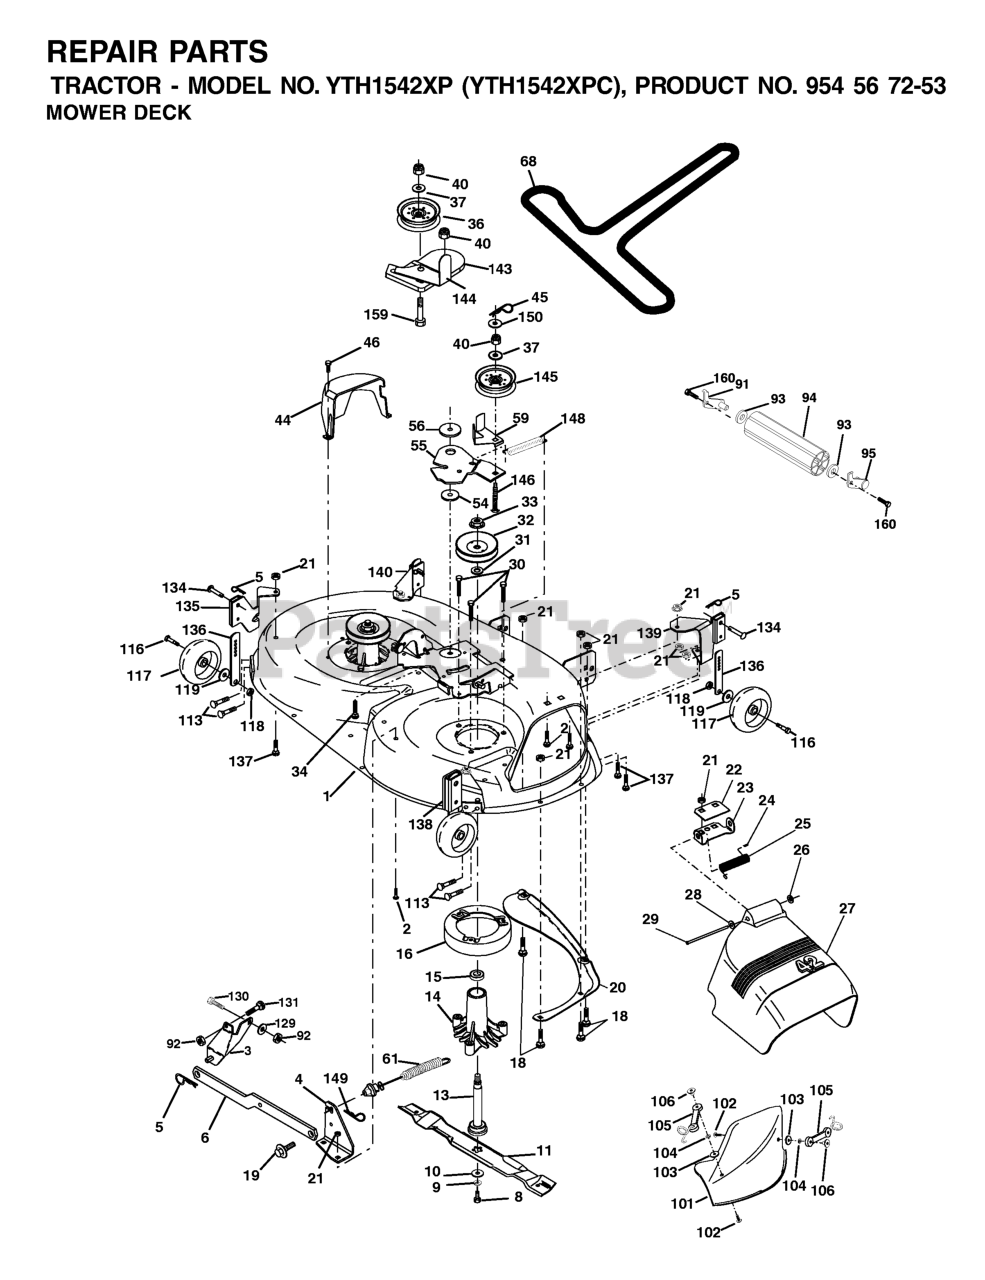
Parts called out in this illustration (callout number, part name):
1	DECK, 42"
2	RP BOLT 5/16-18 X3/4 ZN/YEL GR
3	BRKT ASM SWAY BAR
4	BRACKET SWAY BAR 42" DECK
5	RETAINER-SPRNG RB
6	BAR SWAY DECK
8	BLADE BOLT
9	LOCKWASHER
10	WASHER.BLADE
11	Blade Mower 42" High Perf.
13	SHAFT ASM VENT
14	HOUSING.MANDREL.VENTED (MACHD)
16	STRIPPER.MANDREL.ROUND.BLACK
18	BOLT
19	BOLT SHD 5/16-18
20	BAFFLE.VORTEX
21	LOCKNUT
22	STIFFENER BRACKET
23	DEFLECTOR BRACKET
24	CAP-SLEEVE LT
25	SPRING TORSION
26	NUT PUSH M
27	SHIELD DEFLECTOR
28	Washer 11/32 x 5/8 x 16 Ga SD
29	ROD.HINGE
30	SCREW, WASHER HEAD
31	WASHER
32	PULLEY MANDREL
33	NUT, FLG TOPLOCK 9/16"
36	PULLEY.IDLER.FLAT
37	WASHER
44	GUARD MANDREL LH BLACK
45	RETAINER M
46	SCREW.1/4-20X5/8
54	HARDENED WASHER
55	ARM IDLER 42" MOWER LT/YT
56	SPACER RETAINER
59	GUARD TUV IDLER
61	SPRING EXT ELEC CLUTCH
68	V-BELT PRIMARY 42"
91	BRACKET ASM, ROLLER (L)
92	NUT.71038.31-18.HEX.NYLOCK
93	Washer 1 17/32 X 7/8 X 16 Ga
94	NOSE ROLLER
95	BRACKET ASM, ROLLER
101	COVER MULCH 42"
102	SCREW
104	LOCKWASHER #10
105	LATCH ASSY
106	WELDNUT
113	SCREW 5/16"
116	BOLT M
117	WHEEL.GAUGE.STANDARD
118	LOCKNUT
119	WASHER.5/16.FLAT.STE.STD.
129	WASHER
131	BOLT D
134	RIVET.PIN.HEAD.YELLOW.
135	BRACKET ASM, WHEEL
136	BAR.ADJUST.WHEEL.ANTI.SCALP.BL
137	BOLT.CARR.5/16-18X5/8.SHORT
138	BRACKET.ASM.WHL.GA.R.RH.42".GR
139	BRACKET ASM, WHEEL
140	BRACKET ASM, WHEEL
143	BRACKET, ARM IDLER
144	KEEPER BELT 42" CLUTCH
145	PULLEY.IDLER.FLAT.PLATED
146	BOLT, CARRIAGE IDLER BLACK
148	IDLER RETURN SPRING
149	SPRING.RETAINER.YELLOW.ZINC
160	SCREW 3/8-16X3/4
